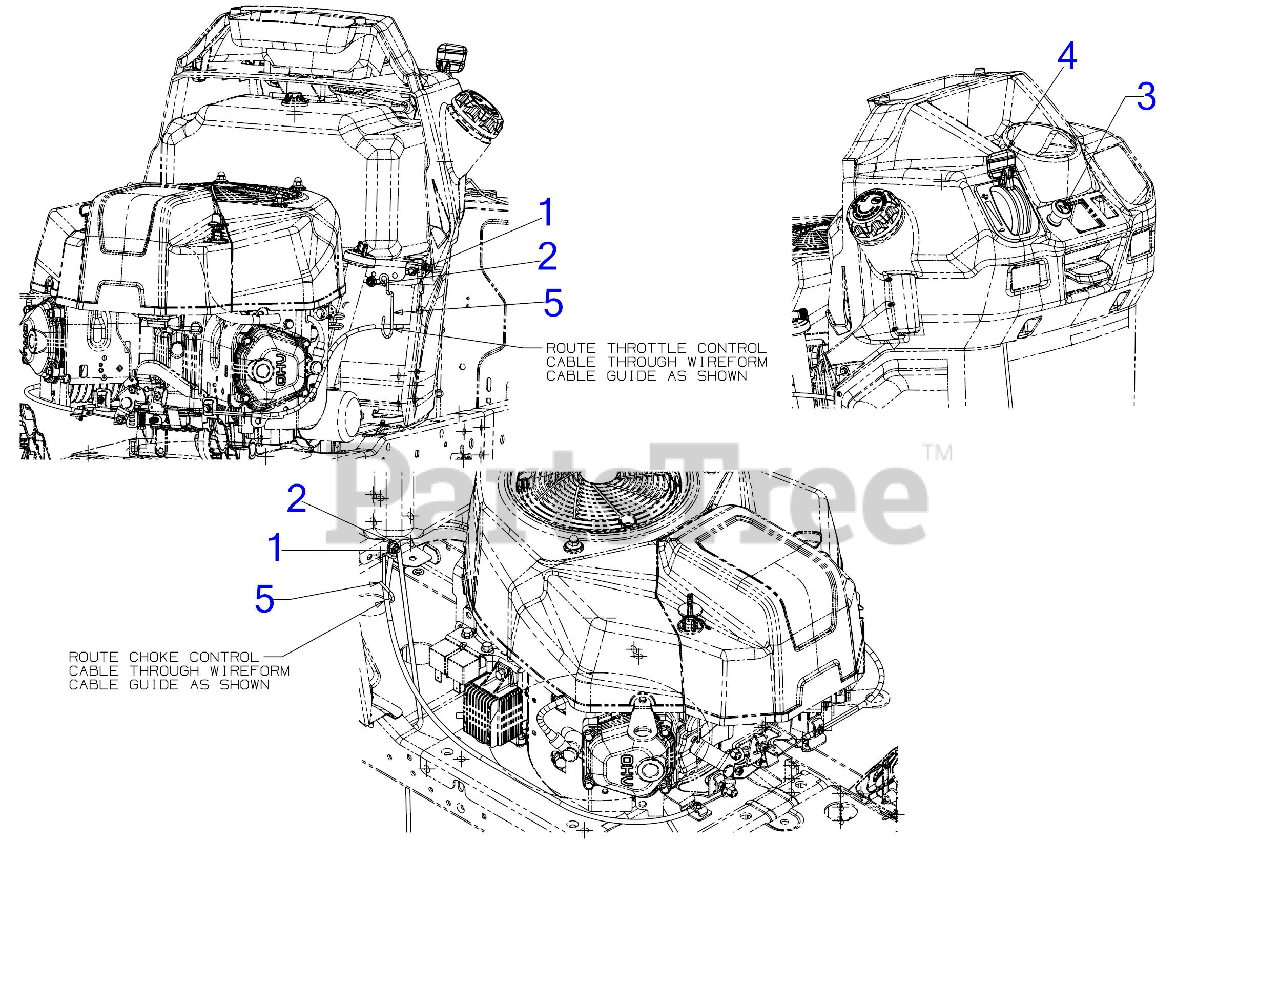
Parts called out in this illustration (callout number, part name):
1	SCREW 1/4-20 x .620 GR5
2	FLANGE LOCK NUT
3	CHOKE CABLE 46.5" x 1.5
4	THROTTLE CABLE 37.5"
5	CABLE GUIDE WIRE
